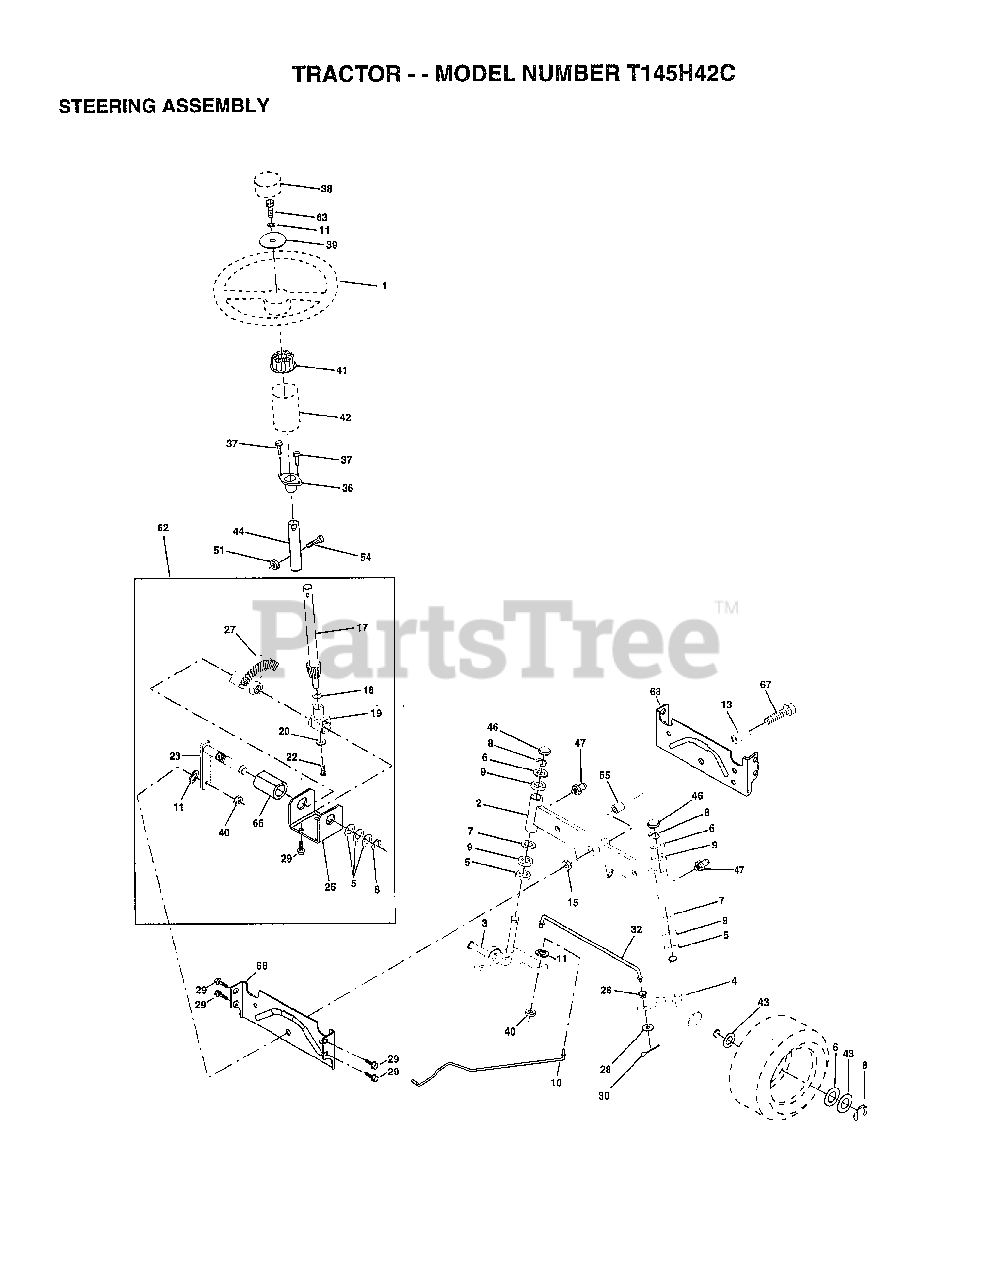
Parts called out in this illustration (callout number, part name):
2	AXLE ASM
3	SPINDLE.ASM.LH
4	"SPINDLE ASM,RH"
5	WASHER .T
6	WASHER
7	WASHER
8	RING
9	COL. SRTG. BEAR.
10	DRAGLINK-STAMPED
11	LOCKWASHER
13	BEARING AXLE
15	"NUT-LOC,FLANGE LT"
17	SHAFT ASM STEERIN
18	THRUST WASHER
19	SUPPORT.SHAFT
22	SCREW HEX SOC1/4-
25	BRKT-STEERING
26	BUSHING.DRAGLINK
27	GEAR SECTOR
28	WASHER
29	SCREW
30	COTTER PIN
32	TIE ROD
36	BUSHING.STEERING
37	"SCREW-TT,10-32 FL"
38	ST WHL INSERT CAP
39	WASHER T
40	GRIPCO NUT
41	ADAPTER LT
42	BOOT.STEER.PL
43	WASHER
44	EXT SHAFT STEERIN
46	CAP
47	ZERK M
51	NUT
54	BOLT
62	KIT STEERING ASM
63	BOLT
65	SPACER AXLE
66	"BEARING-ARM,PITMA"
67	BOLT
68	BRACE AXLE
